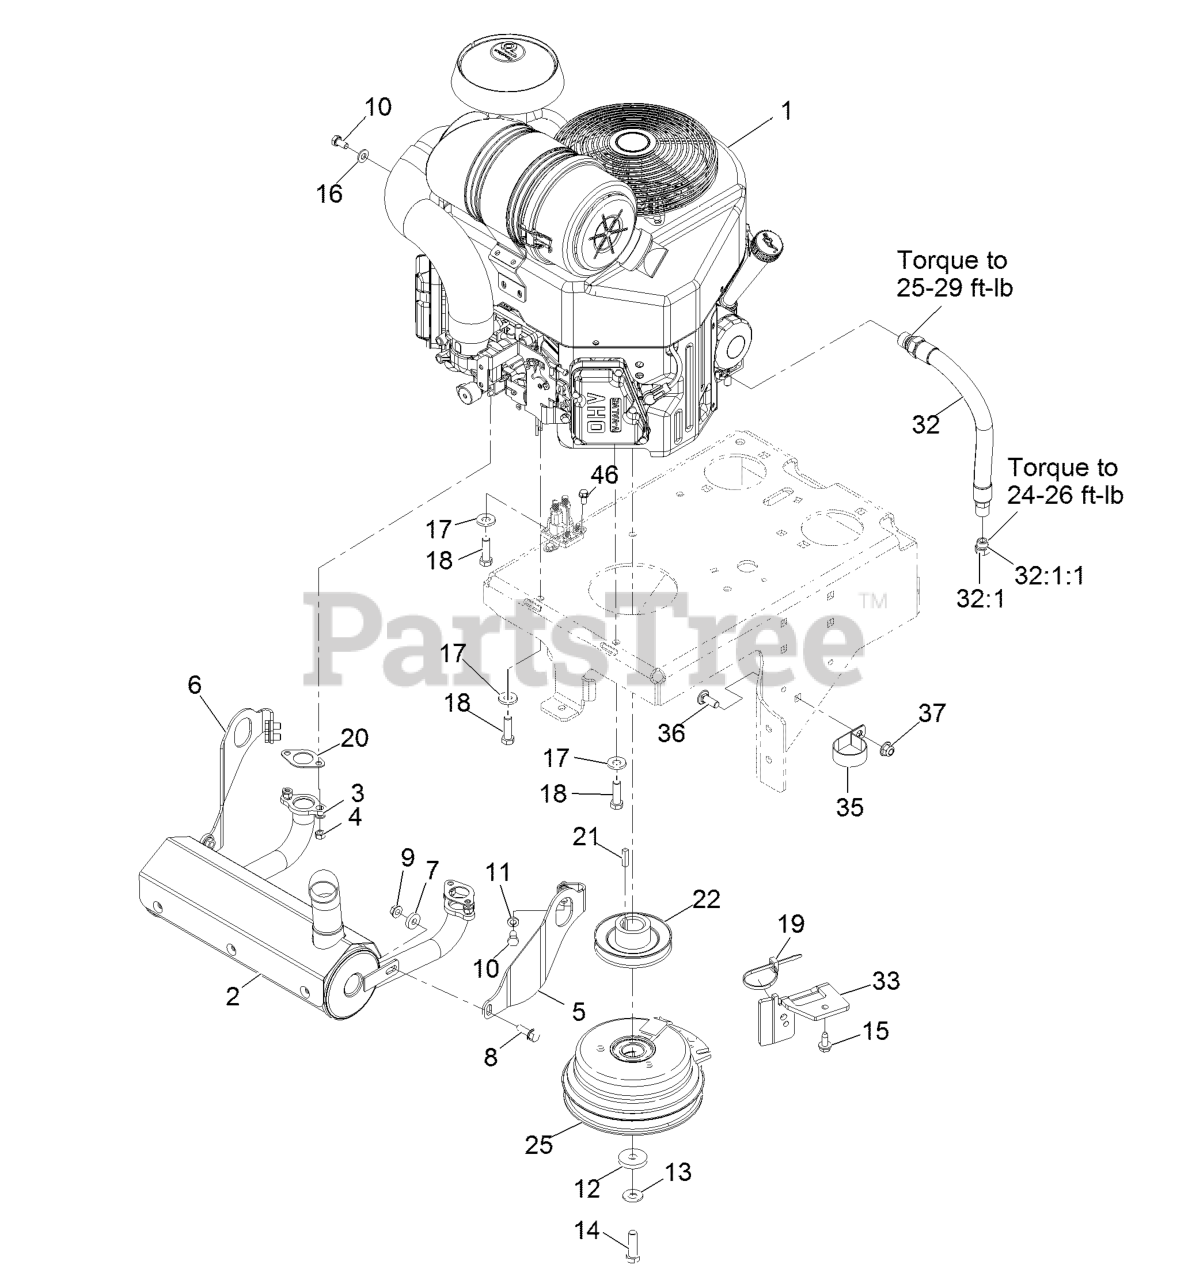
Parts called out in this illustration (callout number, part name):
1	Engine Kawasaki
2	MUFFLER, KAWASAKI, 22-26
3	WASHER-LOCK
5	BRACKET-MUFFLER MOUNT, LH
6	BRACKET-MUFFLER MOUNT, RH
8	SCREW-HHF
10	SCREW-HH
11	WASHER-LOCK
12	WASHER
13	WASHER-SPRING
14	SCREW-HH
15	Screw-HWH 5/16-18 X 3/4 Tf
16	WASHER-PLAIN
17	WASHER-BELLEVILLE
18	SCREW-HH
19	TIE-CABLE
20	GASKET-EXHAUST
25	CLUTCH-200 FT-LB, 1.125 B
32	ENGINE OIL DRAIN HOSE ASM
32:1	PLUG-HH
32:1:1	O-RING
33	BRACKET-ANCHOR, CLUTCH
35	CLAMP-R
36	SCREW-CARR
37	NUT-HF, NI
46	SCREW-HWH
